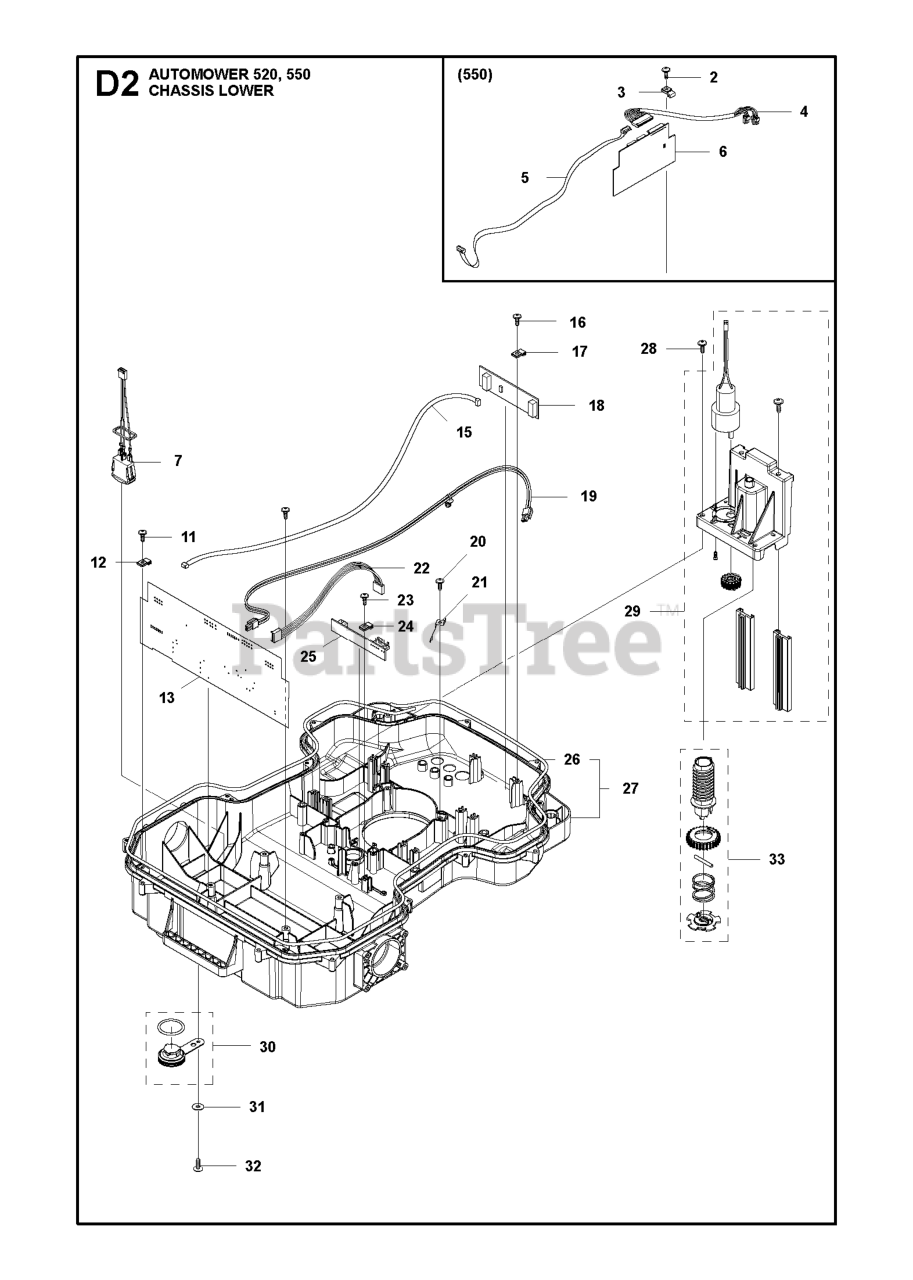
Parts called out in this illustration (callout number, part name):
1	BATTERY LI-ION
2	SCREW 14MM
3	CLAMP PCB
4	LOOM ULTRA SONIC EXTENSION
5	LOOM AUX
6	PRINTED CIRCUIT ASSY ULTRASONI
7	LOOM ON/ OFF
8	HOLDER KIT BATTERY
8	HOLDER BATTERY
9	SCREW ITXPANT
10	HOLDER TWIST LOCK
11	SCREW 14MM
12	CLAMP PCB
13	PRINTED CIRCUIT ASSY PCBA MAIN
15	LOOM LOOP SENSOR
16	SCREW 14MM
17	CLAMP PCB
18	PRINTED CIRCUIT ASSY LOOP SENS
19	LOOM CHARGING LINK HIGH CHARGI
20	SCREW 14MM
21	SPRING GUIDE HEIGHT ADJUSTMENT
22	LOOM HEIGHT ADJUSTMENT
23	SCREW 14MM
24	CLAMP PCB
25	PRINTED CIRCUIT ASSY PCBA CUTT
26	SEALING STRIP
27	CHASSIS KIT LOWER
28	SCREW 14MM
29	MOTOR ASSY HEIGHT MOTOR
30	PLUG KIT
31	WASHER
32	SCREW ITXPANT
33	SCREW KIT
34	WIRING ASSY BATTERY CABLE
